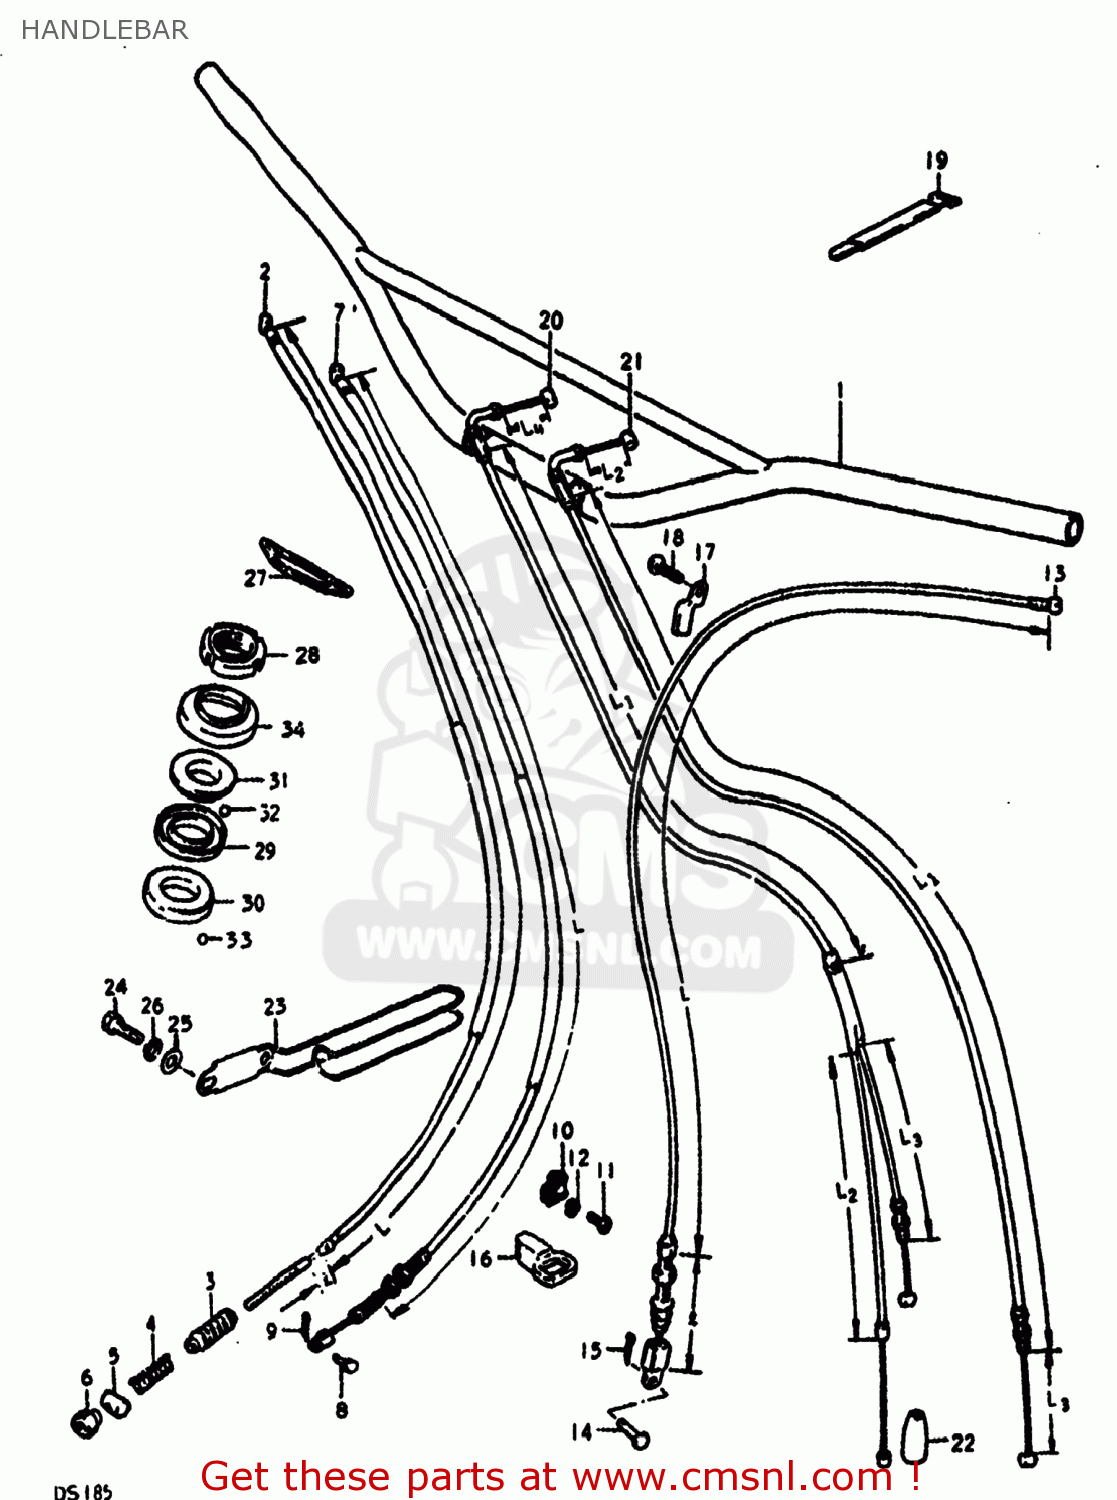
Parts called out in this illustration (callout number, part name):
1	HANDLEBAR
2	CABLE ASSEMBLY,FRONT BRAKE
3	SEAL,DUST(7X16X75)
4	SPRING
5	PIN,10X19
6	NUT
7	CABLE,FRONT BRAKE
8	PIN(L:13.5)
9	PIN
10	GUIDE,CABLE
11	SCREW
12	LOCK WASHER
13	CABLE ASSEMBLY,CLUTCH
14	PIN(L:15)
15	PIN
16	GUIDE,CLUTCH CABLE
17	CLAMP
18	SCREW
19	CLAMP
20	CABLE ASSEMBLY,THROTTLE
21	CABLE ASSEMBLY,THROTTLE
22	SEAL,DUST(7X18X30)
23	GUIDE,CABLE
24	BOLT 8X12
25	WASHER
26	LOCK WASHER
27	GUIDE,CABLE
28	NUT,STEERING STEM(25X44X10)
29	RACE,STEERING INNER UPR
30	LACE,STEERING INNER LWR
31	RACE,STEERING OUTER UPR
32	BALL
33	BALL
34	DUST SEAL,STEERING UPR
